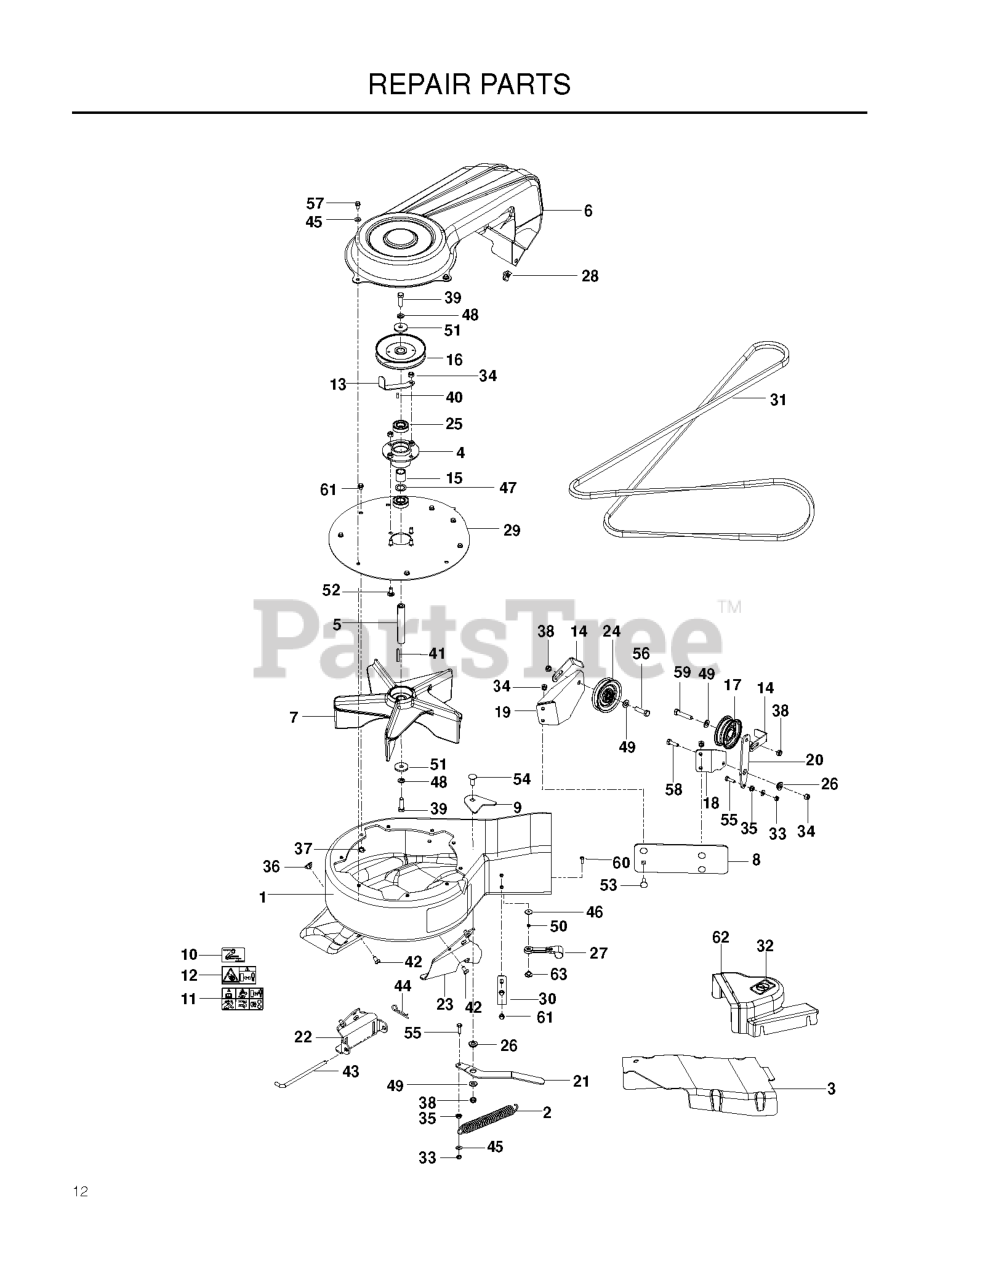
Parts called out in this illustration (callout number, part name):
1	BLOWER.HOUSING.W/DECALS.COLLEC
3	COVER, BELT
4	HUB, BEARING
5	SHAFT, IMPELLER
6	COVER, BELT
7	IMPELLER.COLLECTION.BLOWER.BLA
8	PLATE.BACKING.BLACK
9	PLATE, BACKING
10	DECAL, BELT ROUTING
11	DECAL, EURO WARNING
12	EURO DECAL, IMPELLER
13	KEEPER, BELT, OUTER
14	KEEPER, BELT, REAR
17	IDLER PULLEY
18	MOUNT, IDLER, UPPER
19	MOUNT, IDLER, LOWER
20	ARM, IDLER
21	ARM, TENSION
22	BRKT, MT, FRONT
23	BRKT, MT, REAR
27	HOOD LATCH
28	U-CLIP 5/16-18 NUT RETAINER
29	PLATE, OUTER
32	DECAL, NO STEP
33	JAM NUT 1/4C (2 2 PW01)
34	NUT 5/16 NYLOC
35	NUT 1/4-20 HEX FLG LK ZD
36	NUT 5/16-18 TEE
37	NUT 1/4-20 TEE
38	NUT HEX 3/8-16 NYLON, THIN
39	BOLT, HEX 3/8-24 X 1.25 GR 8
40	KEY, 3/16 X 1/2
41	KEY-SQ. 3/16 X 1 1/2
42	HCS 5/16-18 X 1/2 GR 5 ZD
44	HAIRPIN #2
45	WASHER 1/4 SAE
47	WASHER .787 X 1.125 X .06
48	SLW 3/8 STD
49	WASHER 3/8 SAE FLAT
50	WASHER - 3/16 LOCK ZD
51	WASHER, HARDENED
52	BOLT 5/16C X 3/4" CARRIAGE
53	RHSNB 5/16C X 1
54	RHSNB 3/8C X 1
55	HCS 1/4-20X7/8 GR5
56	HCS 3/8C X 1 1/2
57	BOLT 1/4-20 X 1/2 HWST
58	HCS 5/16C X 1
59	BOLT, HCS 3/8-16X1-3/4
60	SCREW #10-24 X 5/8
61	HWST 1/4C X 3/8
62	SHIELD, BELT, 42"
63	NUT 10-24 WELD PLATED
